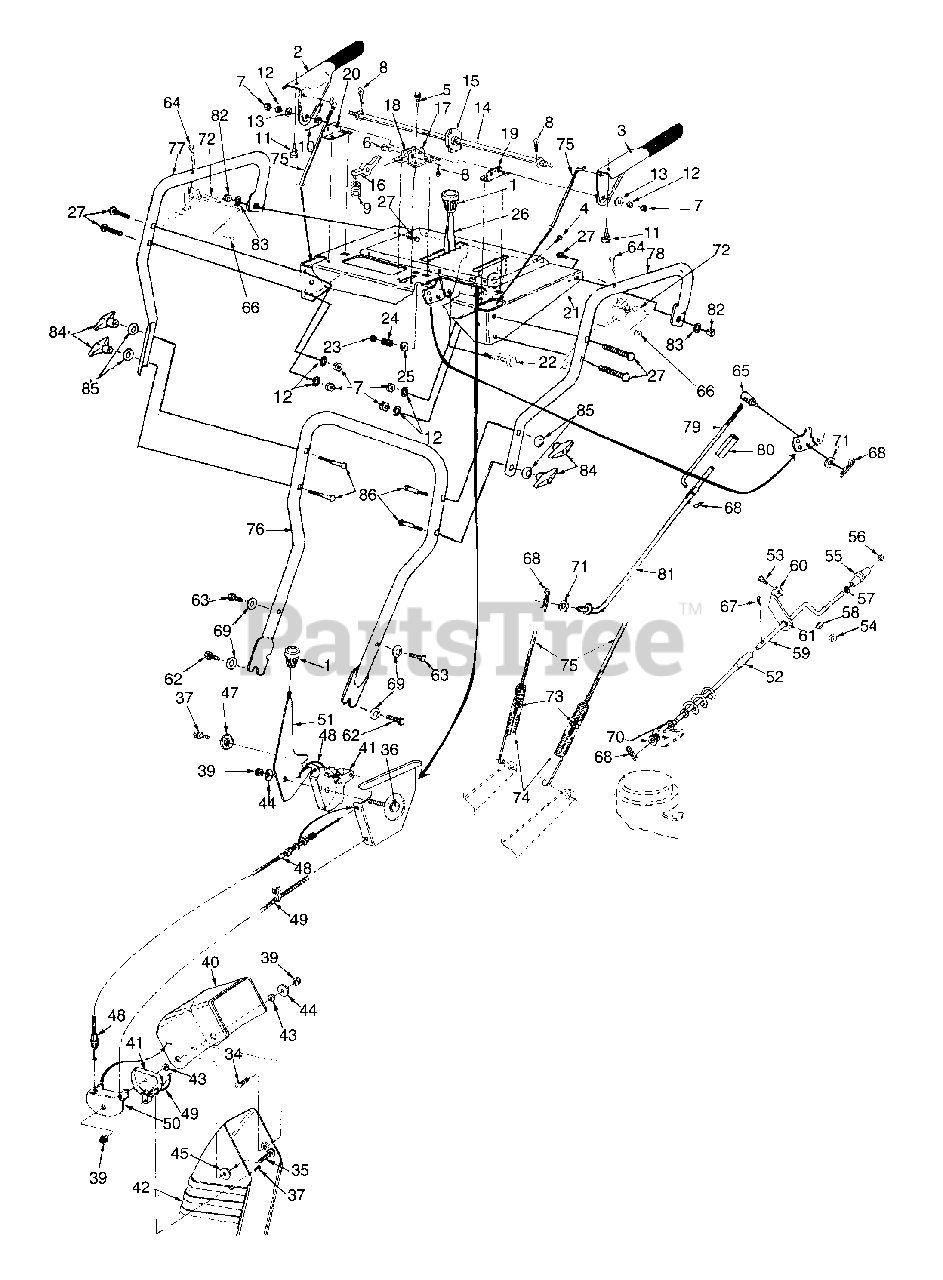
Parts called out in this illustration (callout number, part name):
1	Shift Knob
2	Engage Handle Le Blk Dip Rh
3	Engage Handle Lf Blk Dip Lh
4	Pan Head B-tapp Scr #10 x .5
5	Hwhd Sf-tap Scr 1/4-20 x 1/2 Lg.
6	Clevis Pin .31 Dia. x 1.0
7	Nut Hex 5/16-18 Gd 5
8	Cot-pin 3/32 Dia. x 1.0
9	Comp Spring .36 Dia. x 1.0 Lg
10	Spring Torsion .44 ID
11	Rubber Bumper .63 Dia.
12	Lock Washer 5/16
13	Wsher Spcl. .345 I.D. x .72 OD
14	Cam Rod
15	Clutch Lock Cam
16	Clutch Lock Pawl
17	Supt Brkt 5/8 L.H.
18	Supt Brkt 5/8 R.H.
20	Supt Brkt 3/8 R.H.
22	Scr Hex Cap 3/8-24 x 1.5 Gd 5
23	Hex Ins L-nut 3/8-24
24	Compression Spring .39 ID x .88
25	Bell Wash .40 ID x .88 OD x .06
26	Shift Handle
27	Carriage Bolt 5/16-18 x 1.75
34	Carriage Bolt 5/16-18 x 1.00
35	Carriage Bolt 5/16-18 x 1.75
36	Hex Scr 5/16-18 x 1.5
37	HWHD B Tapp Scr 1/4 x 5/8 Lg.
39	Hex Ins L-nut 5/16-18
40	6" Upper Chute Remote Tilt
41	Chute Tilt Cable Guide
42	6" Lower Chute Remote Tilt
43	Chute Pivot Spacer
44	Fl-wash .344 ID x .88 OD x .063
45	Flt Wshr .344 x 1.125 x .125
47	Contoured Washer
48	Chute Control Cable 66"
49	Chute Control Cable 66" W/clip
51	Chute Tilt Handle
52	Chute Crank Assy Plated
53	Hex Scr 1/4-20 x .75 Lg Gd5
54	Hex Nut 1/4-20
55	Chute Crank Knob
56	Push Cap 3/8 Palnut #375011
57	Flat Washer .38 ID x .60 OD x .033
58	Bell Wash .26 ID x .75 OD x .06T
59	Crank Chute Plated
60	Brkt Chute Crank
61	Plastic Bushing .380 ID
62	Hex Scr 3/8-16 x .75
63	Hex Scr 3/8-16 x 1.75
64	Scr Oval C/sunk #10-24 x 1.75
65	Adjustment Ferrule
66	#10-24 Flat Weld Nut
67	Internal Cot-pin 1/2 Dia.
68	Inter Cot-pin 5/16 Dia.
69	Bell Wash .4 ID x .88 OD x .06
70	Fl-wash .406 ID x .74 OD x .063
71	Fl-wash Sae .34 x .68 x .062
72	Trigger Ass'y Steer
73	Hex Ins L-nut 1/4-20
74	Extension Spring
75	Cable Clutch Drive
79	Upper Shift Rod 5/16 x 10.57
80	2 Pc Shift Rod Connector
81	Lower Shift Rod 3/8 x 14.75
82	Hex Nut 1/4 - 20
83	Bell Wash .26 ID x .75 OD x .06T
84	Wingnut
85	Bell Wash .345 ID x .88 OD x .060
86	Carriage Bolt 5/16 -18 x 2.5
